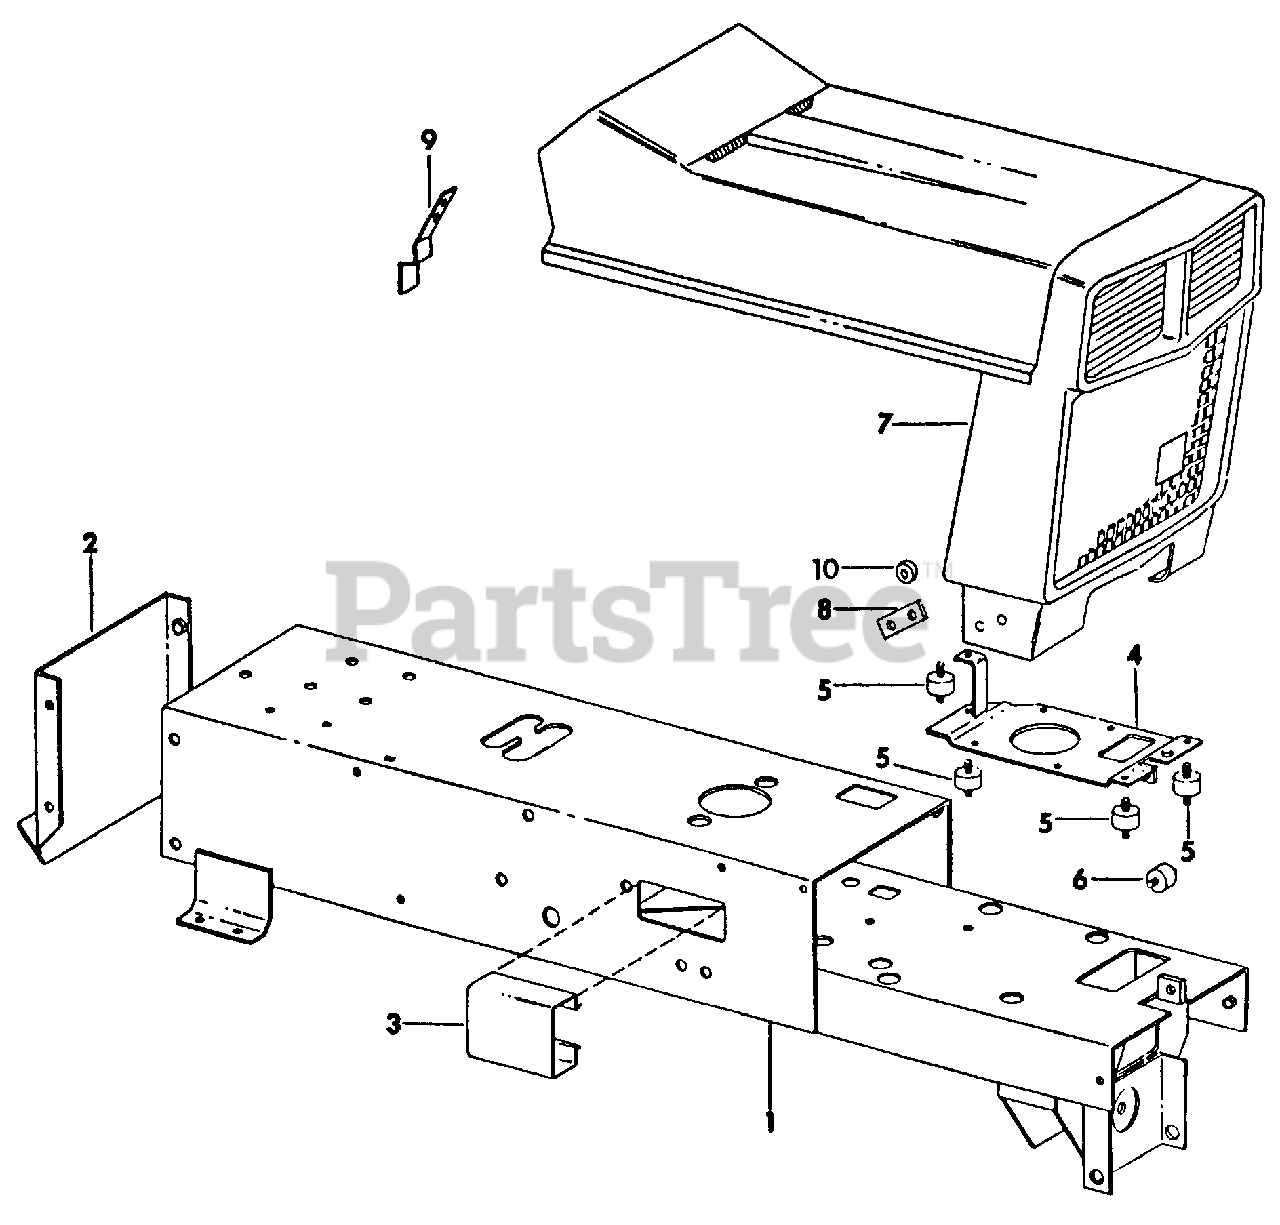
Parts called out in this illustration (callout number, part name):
1	Frame Assy
2	Drawbar Assy
3	Cover, Steering Arm
4	Plate Assy, Engine Mounting
5	Mount, Cylindrical
7	Hood Assy
8	Bracket, Hood Front Mounting
9	Latch, Hood
10	Spacer, Rubber
